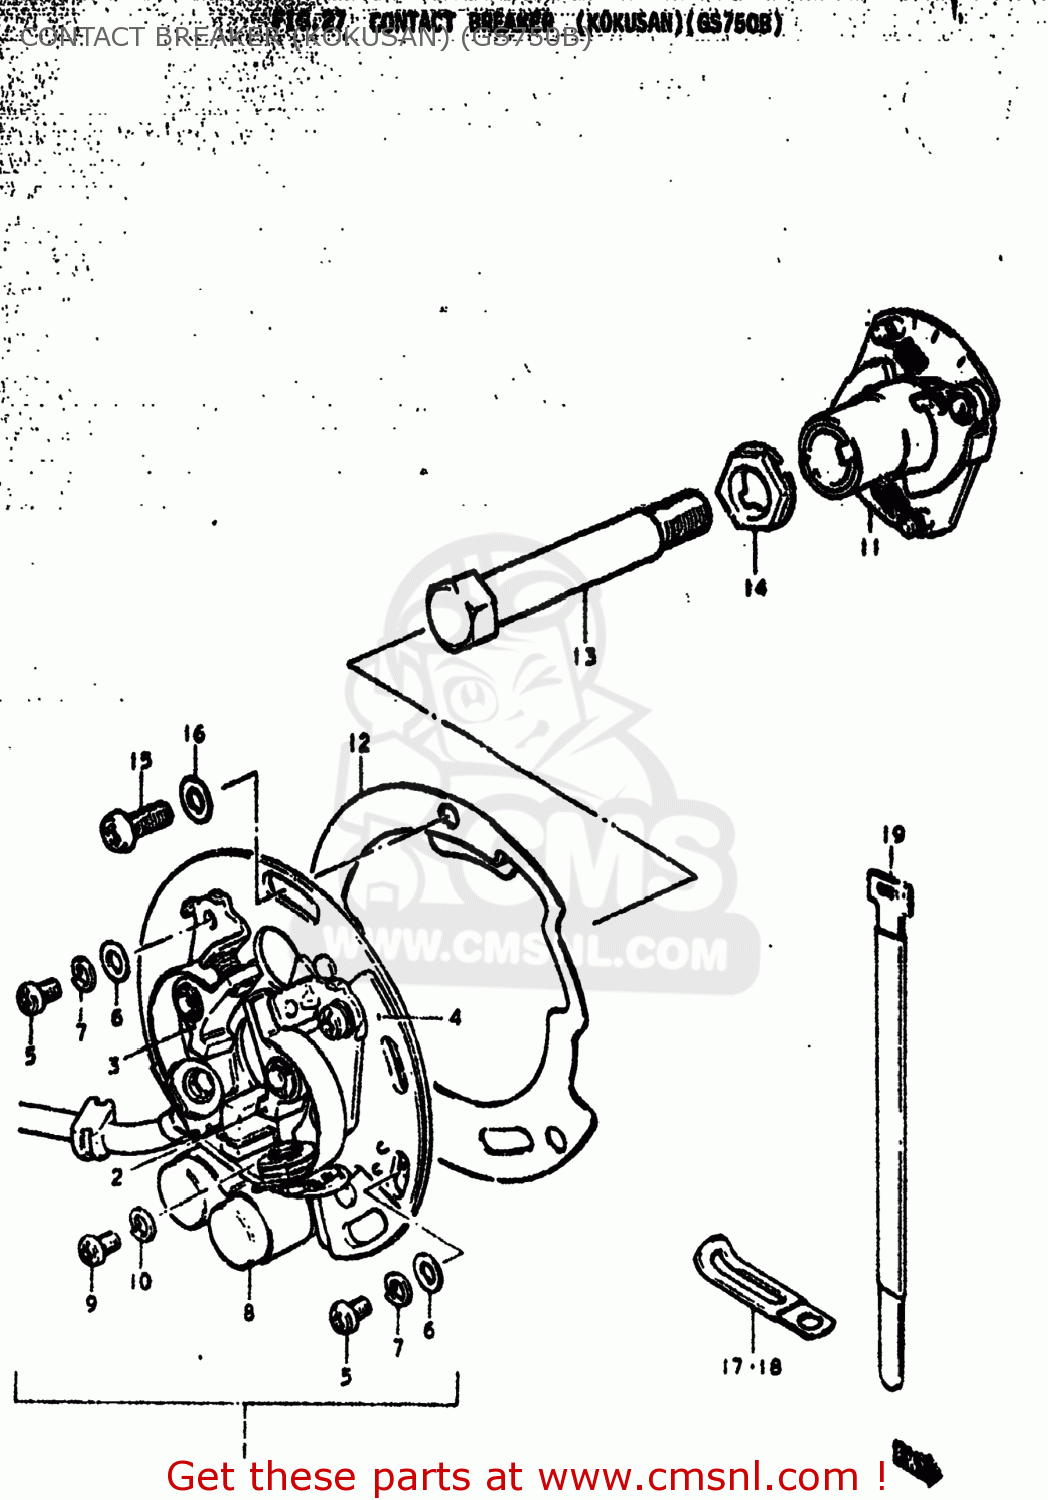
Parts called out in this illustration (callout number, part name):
1	BREAKER ASSEMBLY,CONTACT
2	POINT ASSEMBLY,CONTACT
3	POINT ASSEMBLY,CONTACT
4	PLATE,CONTACT POINT
5	SCREW
6	WASHER
7	LOCK WASHER
8	CONDENSER
9	SCREW
10	LOCK WASHER
11	GOVERNOR ASSEMBLY
12	PLATE,IGNITION TIMING
13	BOLT
14	WASHER
15	SCREW(5X12)
16	WASHER 5MM
17	CLAMP L:35
18	CLAMP
19	CLAMP
